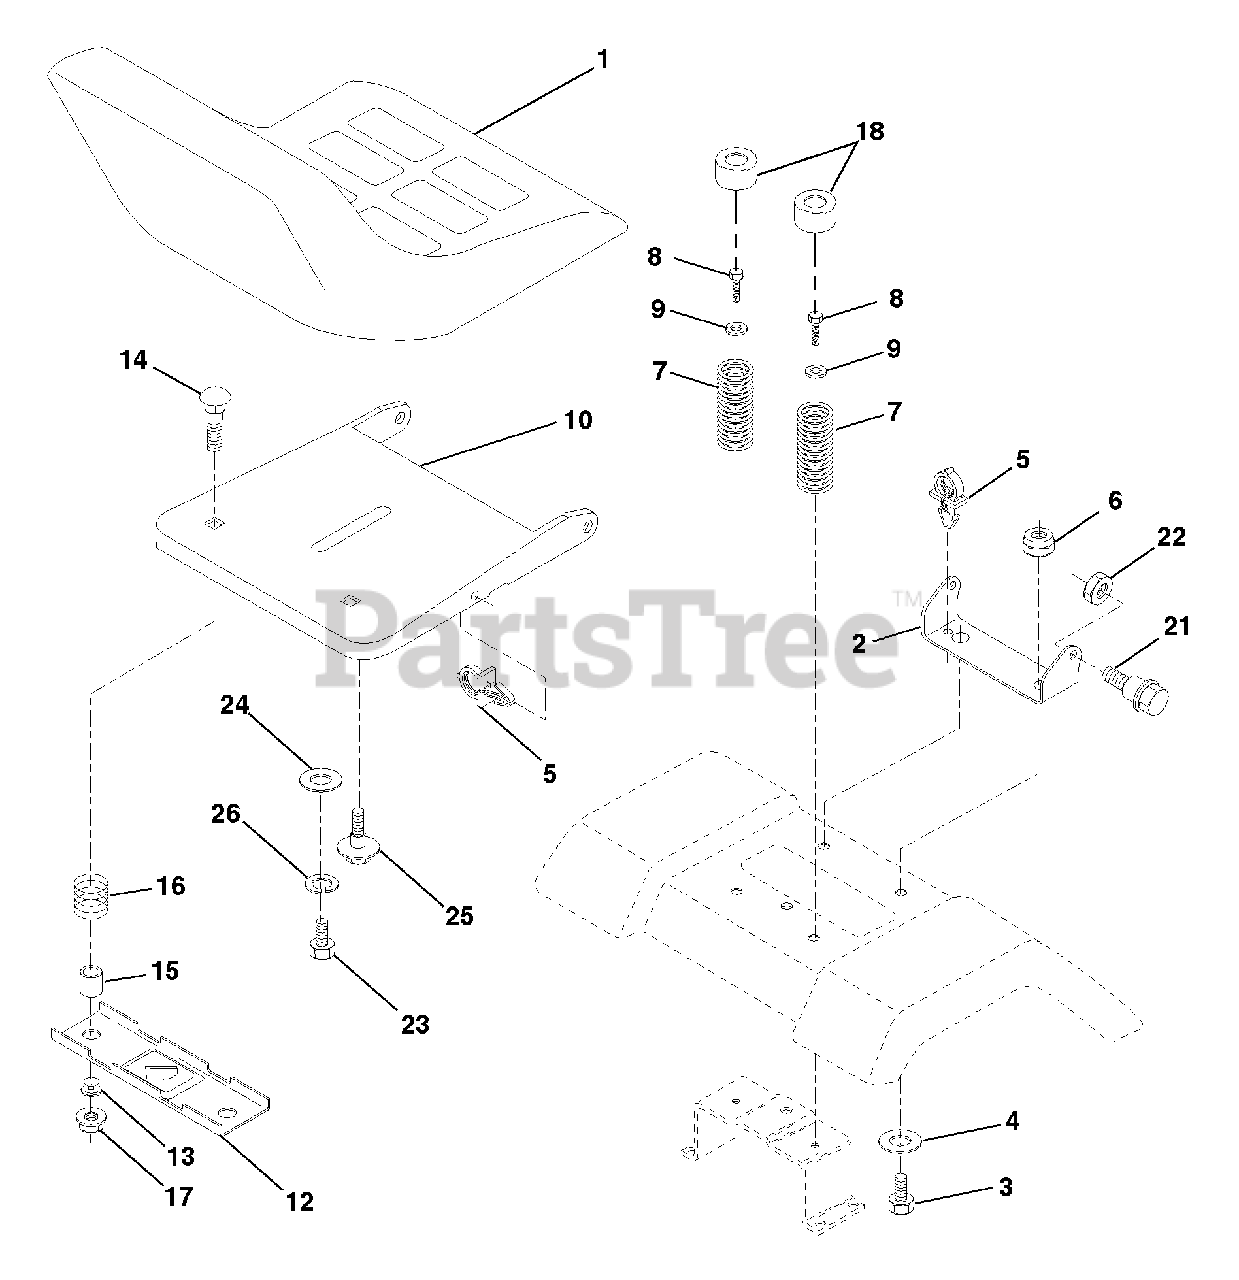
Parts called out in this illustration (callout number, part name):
1	Seat
2	Bracket Pivot Seat 8 720
3	Bolt Fin Hex 3/8-16 unc X 1
4	Washer 13/32 X 1 X 10 Ga
5	Clip Push-In
6	Nut Hex w/Ins. 3/8-16 Unc
7	Spring Seat Cprsn 2 250 Blk Zi
8	Screw Thdrol 3/8-16 X 1 Ty-tt
9	Washer 13/32 X 1 X 14 Ga.
10	Pan Seat
12	Bracket Mounting Switch
13	Bushing Snap Blk Nyl 50 Id
14	Bolt Rdhd Sqnk 1/4-20 x 1-3/8
15	Spacer Split 28 x .88 Zinc
16	Spring Cprsn Plate
17	Nut Lock 1/4 Lge Flg Gr 5 Zinc
18	Cap Spring Seat
21	Bolt Shoulder 5/16-18 Unc
22	Nut Hex Lock W/Ins 5/16-18
23	Bolt, Hex Head, Fin 1/2-13 x 7/8 Grade 5
24	Washer 17/32 X 1-3/16 X 12 Ga.
25	Bolt Shoulder 5/16-18 X 62
26	Washer Lock
